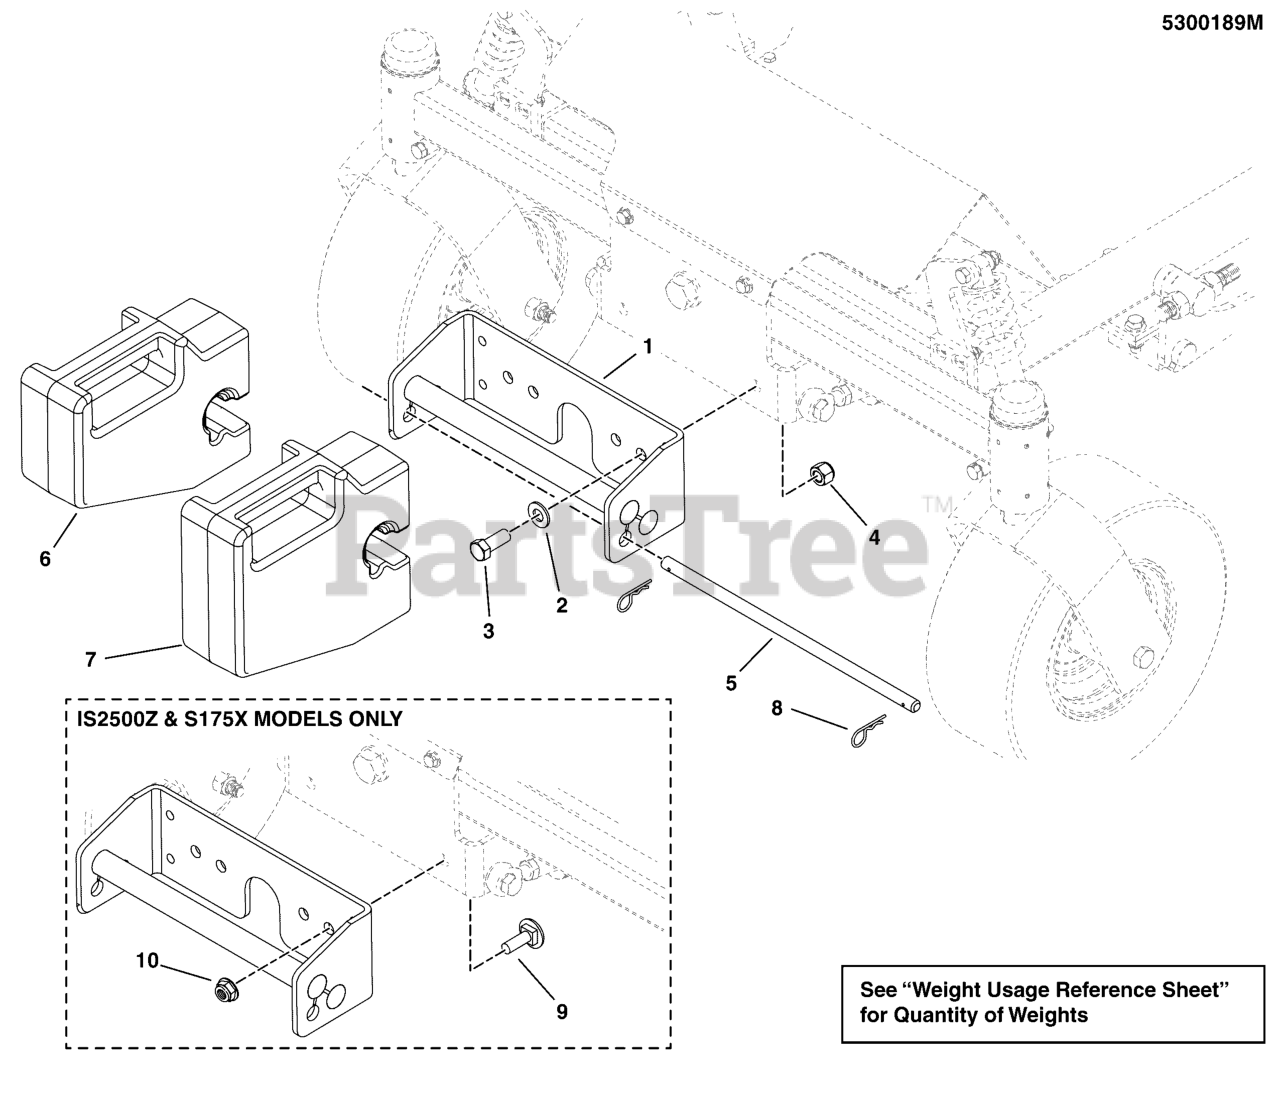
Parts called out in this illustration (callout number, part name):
1	HOLDER ASMY-WEIGHT CONS Z CAT - BLACK
2	WASHER, 1/2 SAE
3	BOLT, 1/2-20 X 1-1/4" GD5 CZ
4	NUT, Hex, Nylon Lock, 1/2-20
5	ROD-.500DIA 13.75LG YELLOW CON
6	WEIGHT-QUICK ATTACH 33LBS PAINTED BLACK
7	WEIGHT-QUICK ATTACH 50LB SUITCASE PAINTED
8	PIN, HAIR, .0915 X 1-7/8
9	BOLT, CARRIAGE 1/2-13 X 1-1/4 GD.5
10	NUT, Hex Flange, Nylock, 1/2-13
